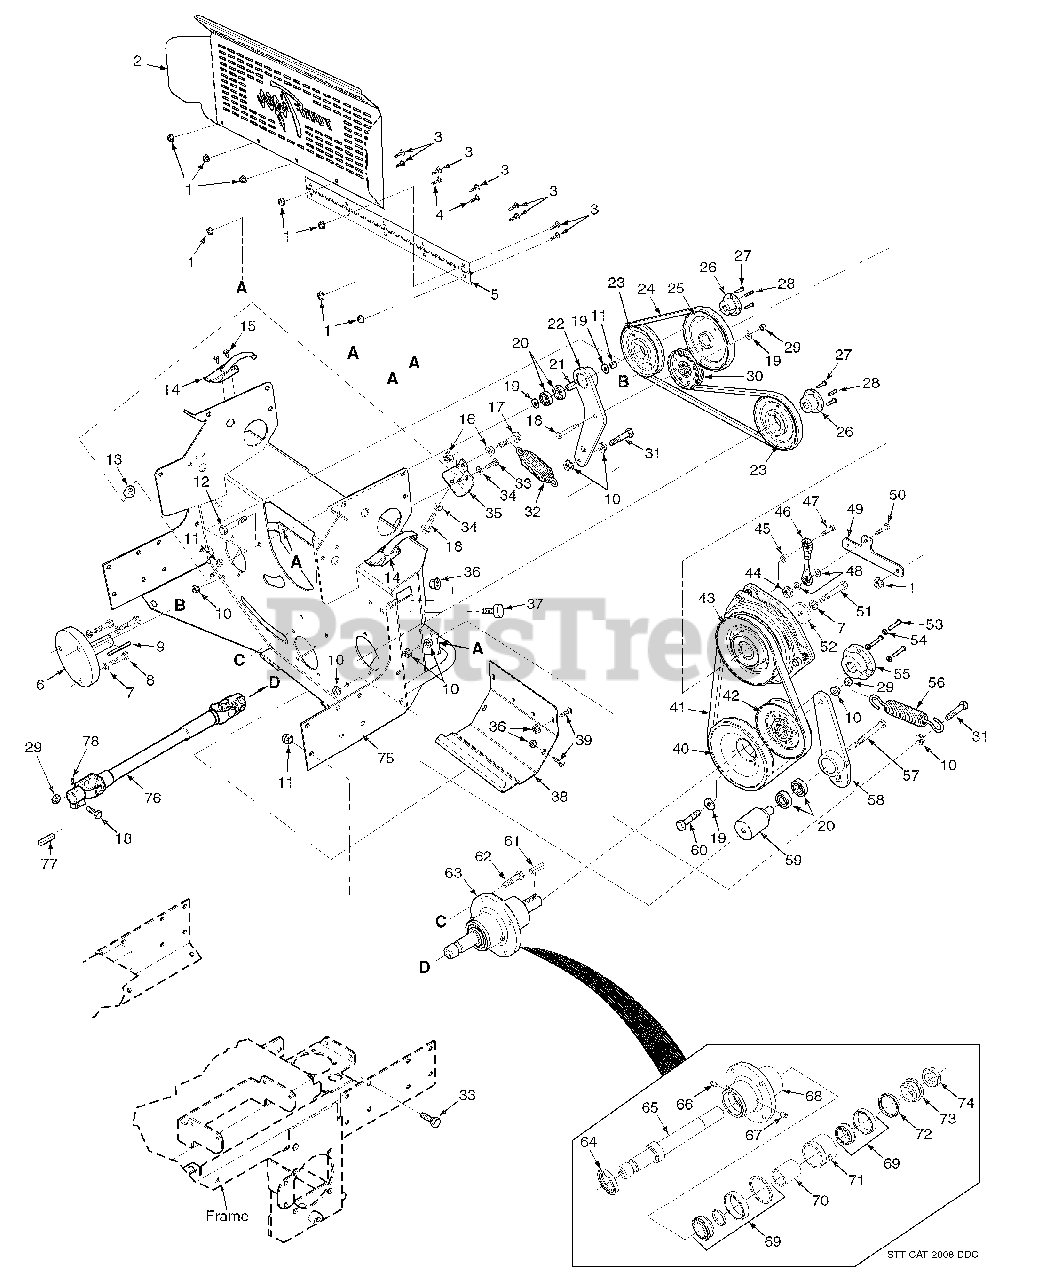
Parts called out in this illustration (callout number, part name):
1	Nut, Serrated Flange 1/4-20
2	Belt Guard, Rear
3	Bolt, Carriage 1/4-20 x 1/2”
4	Bolt, Carriage 1/4-20 x 3/4”
5	Hinge, Belt Guard
6	Stub Shaft
7	Lockwasher, 7/16” Spring
8	Bolt, Hex Head M10 x 1.5 x 35
9	Key, 1/4 x 1/4 x 3-1/4”
10	Nut, Serrated Flange 3/8-16
11	Nut, Elastic Stop 3/8-16
12	Bolt, Hex Head 3/8-16 x 1-3/4” Grd 8
13	Spacer
14	Latch, Hood
15	Screw, #10-32 x .56
16	Nut, Serrated Flange 1/2-13
17	Bolt, Hex Head 1/2-13 x 2” Grd 8
18	Bolt, Hex Head 3/8-16 x 1-3/4”
19	Washer, 3/8” Hardened
20	Ball Bearing
21	Spacer, Idler Bearing
22	Idler Arm Weldment, Pump Drive
23	Pulley, 5.75” O.D.
24	Belt, Pump Drive
25	Pulley, 6.35 Dia. - 1.125 Bore
26	Tapered Hub, 17mm Bore
27	Bolt, Hex Head 1/4-20 x 1” Grd 8
28	Key, 5 x 5 x 35 mm
29	Nut, Center Lock 3/8-16
30	Pulley, Idler 4” Dia.
31	Bolt, Hex Head 3/8-16 x 1-1/2” Grd 8
32	Spring, Transmission Idler
33	Bolt, Hex Head 3/8-16 x 1”
34	Flatwasher, 3/8-.391 x .938 x .105
35	Bracket
36	Nut, Serrated Flange 5/16-18
37	Bumper, Rubber
38	Cover, Rear
39	Bolt, Carriage 5/16-18 x 3/4”
40	Pulley, 6.35 Tapered Bore
41	Belt, Deck Drive
42	Pulley, Idler 5” Dia.
43	Clutch, Ogura GT 3.5 - 1.125 Bore
44	Nut, Hex Elastic Stop 5/16-18
45	Spacer
46	Rod Assembly, Clutch Anti-Rotation
47	Bolt, Hex Head 5/16-18 x 1-1/2”
48	Flatwasher, 5/16”
49	Bracket, Anchor, Anti-Rotation
50	Bolt, Hex Head 5/16-18 x 1-1/4”
51	Bolt, Hex Head 7/16-20 x 2-1/4”
52	Flatwasher, 7/16-.469 x 1.75 x .25
53	Bolt, Hex Head 1/4-20 x 1-3/8”
54	Lockwasher, 1/4” Spring
55	Tapered Hub, 1” Bore
56	Spring, PTO
57	Bolt, Hex Head 3/8-16 x 4-1/2” Grd 8
58	Idler Arm Weldment, PTO Drive
59	Pivot, Idler PTO
60	Bolt, Hex Head 3/8-16 x 2-1/2” Grd 8
61	Key, 1/4 x 1/4 x 1-1/2”
62	Bolt, Hex Head 5/16-18 x 1-3/4” Grd 8
63	Spindle Assembly, Deck Drive
64	Seal, 2.0 OD x 1.5 Bore
65	Shaft, Deck Drive
66	Grease Fitting, 1/4-28
67	Relief Fitting
68	Spindle Housing
69	Roller Bearing Tapered
70	Spacer, Inside
71	Spacer, Outside
72	Seal, 2.0 OD x 1.625 Bore
73	Spindle Bushing, Bottom
74	Nut, 1.06-18 Thread
75	Pump Mounting Plate Weldment
76	Driveshaft
77	Key, 1/4 x 1/4 x 1”
78	Set Screw, 3/8-16 x 3/4” Torx Socket
